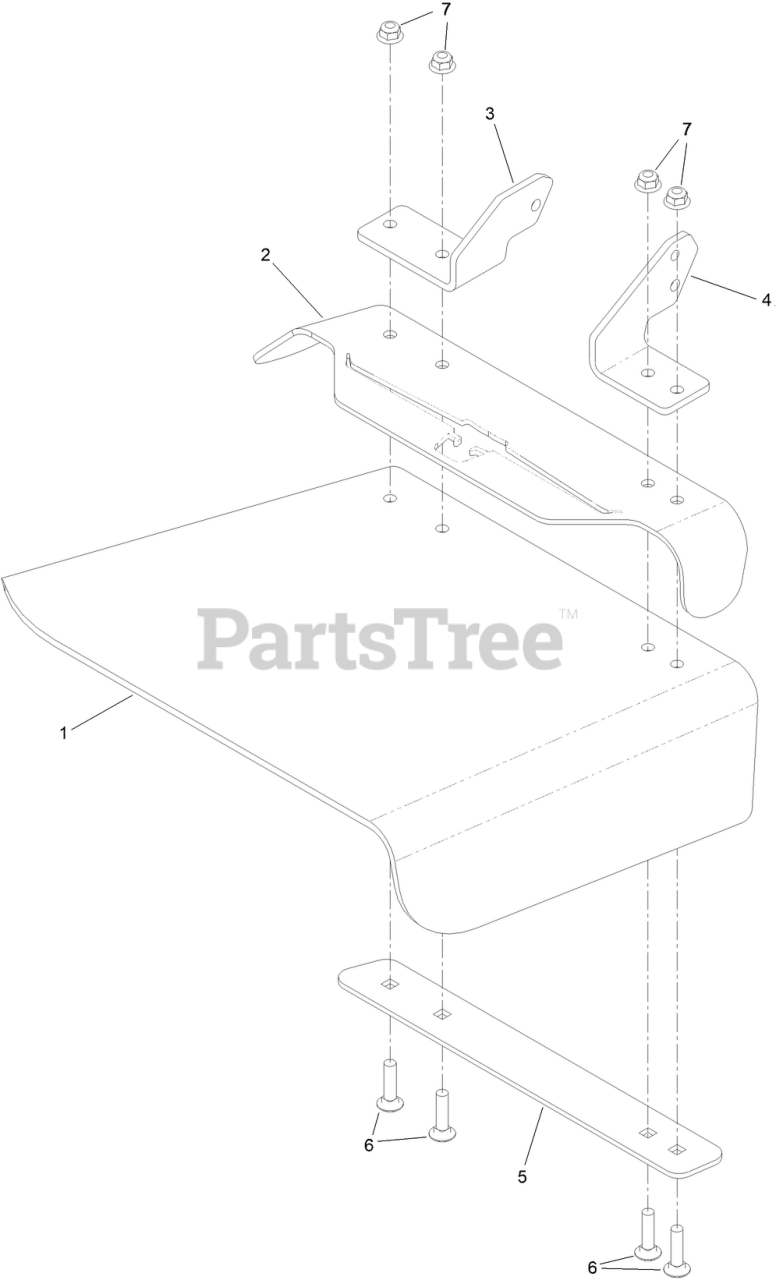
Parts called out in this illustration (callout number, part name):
1	DEFLECTOR-RUBBER
2	PLATE-DEFLECTOR MOUNT
3	PLATE-HINGE, REAR
4	PLATE-HINGE, FRONT
5	STRAP-DISCHARGE
6	SCREW-CARR
7	NUT-HF, NI
